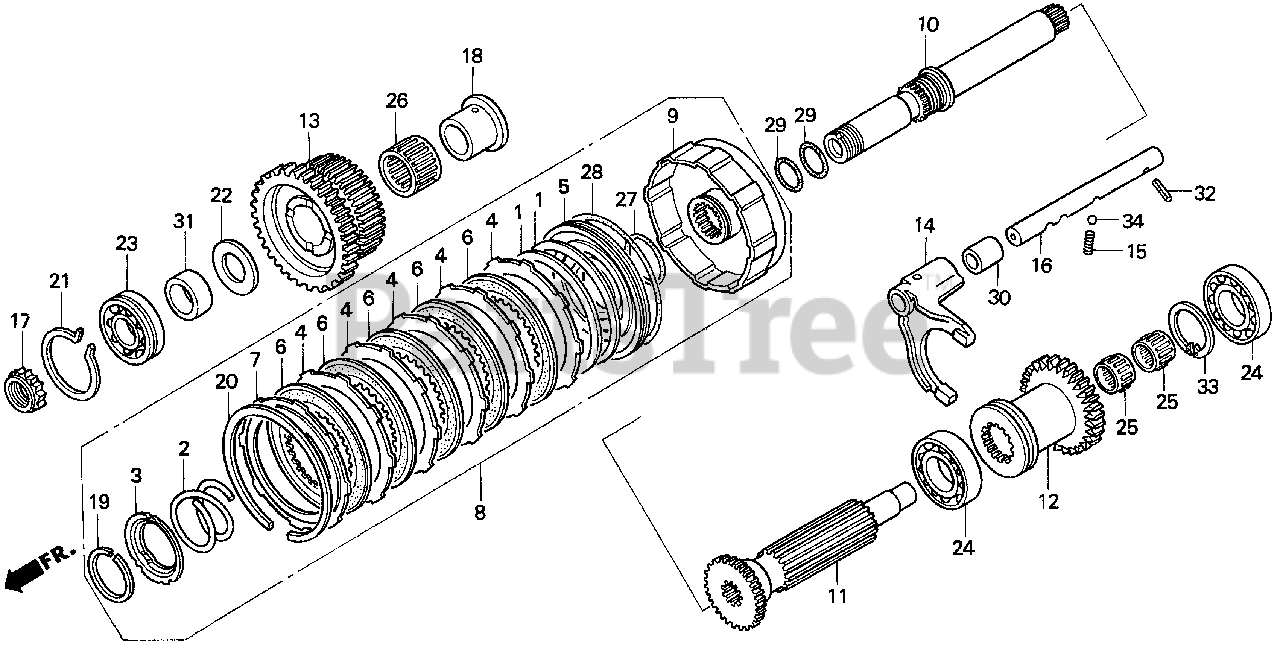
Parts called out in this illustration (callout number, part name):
1	SPRING, CLUTCH DISK
2	SPRING, CLUTCH RETURN
3	SEAT, CLUTCH SPRING
4	PLATE, CLUTCH (106)
5	PISTON, CLUTCH
6	DISK, CLUTCH
7	PLATE, CLUTCH END (2.3MM)
7	PLATE, CLUTCH END (2.6MM)
7	PLATE, CLUTCH END (2.9MM)
7	PLATE, CLUTCH END (3.2MM)
7	PLATE, CLUTCH END (3.5MM)
7	PLATE, CLUTCH END (2.15MM)
7	PLATE, CLUTCH END (2.45MM)
7	PLATE, CLUTCH END (2.75MM)
7	PLATE, CLUTCH END (3.05MM)
7	PLATE, CLUTCH END (3.35MM)
7	PLATE, CLUTCH END (3.65MM)
8	CLUTCH ASSY., P.T.O.
9	GUIDE, P.T.O. CLUTCH
10	COUNTERSHAFT A, P.T.O.
11	COUNTERSHAFT, P.T.O. (C)
12	GEAR, MIDDLE P.T.O. DRIVE (28T)
13	GEAR, P.T.O. DRIVEN (38T-38T)
14	FORK, P.T.O. SHIFT
15	SPRING, BALL SETTING
16	SHAFT, P.T.O. SHIFT
17	NUT, LOCK (25MM)
18	COLLAR, DISTANCE (25X32X30)
19	CIRCLIP (OUTER) (40MM) (F.C.C.)
20	RING, SNAP (114X1.8)
21	RING, SNAP (52MM)
22	WASHER, THRUST (25X45X4.0)
23	BEARING, BALL (6205C)
24	BEARING, RADIAL BALL (60/32)
25	BEARING, NEEDLE (17X21X10)
26	BEARING, NEEDLE (32X37X27) (TOYO)
27	O-RING (39.8X2.2) (ARAI)
28	O-RING (100X2.2) (NOK)
29	O-RING (31.2X1.9) (ARAI)
30	COLLAR (14.5X19.1X21.8)
31	COLLAR, DISTANCE (25MM)
32	PIN, SPRING (3X18)
33	CIRCLIP (INNER) (58MM)
34	BALL, STEEL (#10) (5/16)
